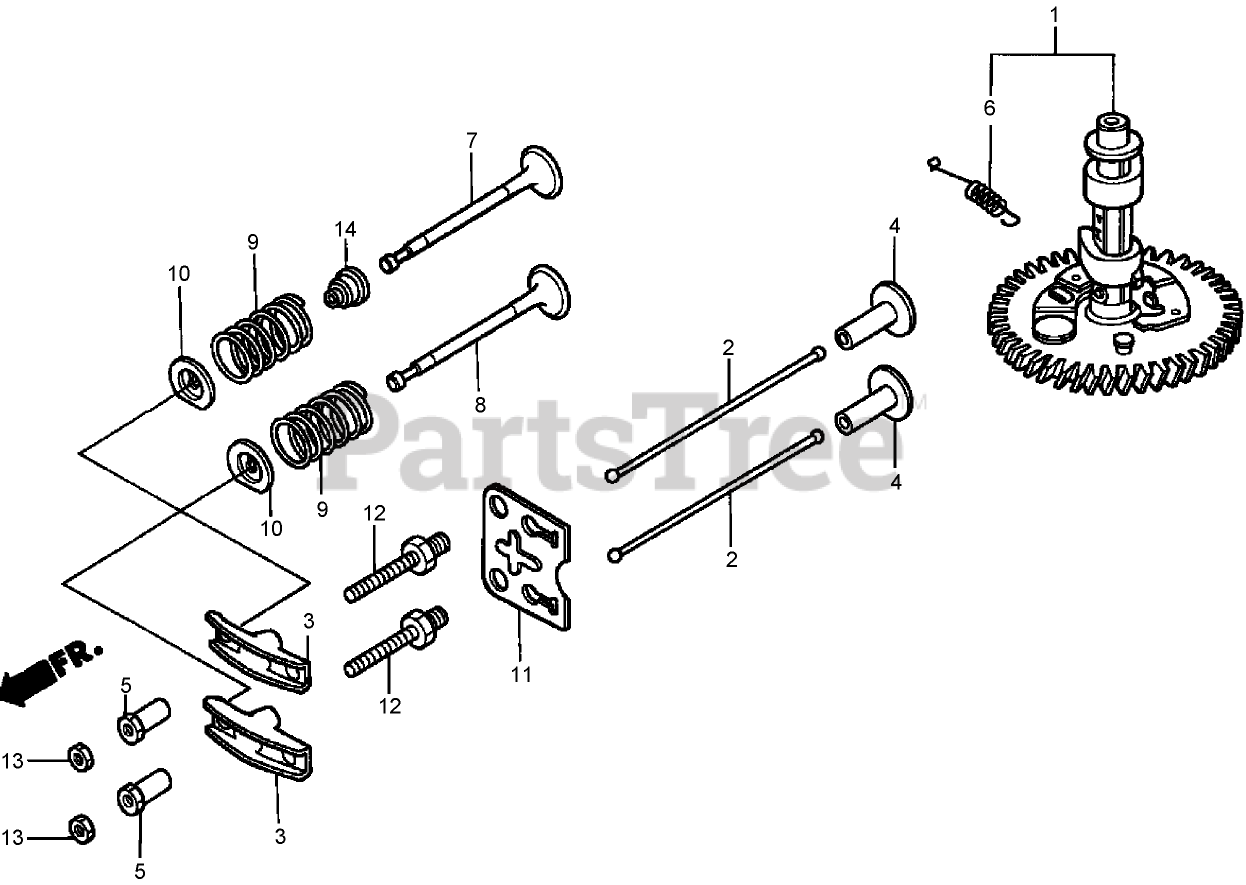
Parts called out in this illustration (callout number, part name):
1	CAMSHAFT ASM
2	ROD-PUSH
3	ARM-ROCKER, VALVE
4	Lifter-Valve
5	PIVOT-ARM, ROCKER
6	SPRING-RETURN, WEIGHT
7	VALVE-INTAKE
8	VALVE-EXHAUST
9	Spring-Valve
10	RETAINER-SPRING, VALVE (INTAKE)
11	Plate-GUIDE, Push Rod
12	BOLT-PIVOT (8 mm)
13	NUT-ADJUSTING, PIVOT
14	SEAL-STEM, VALVE
